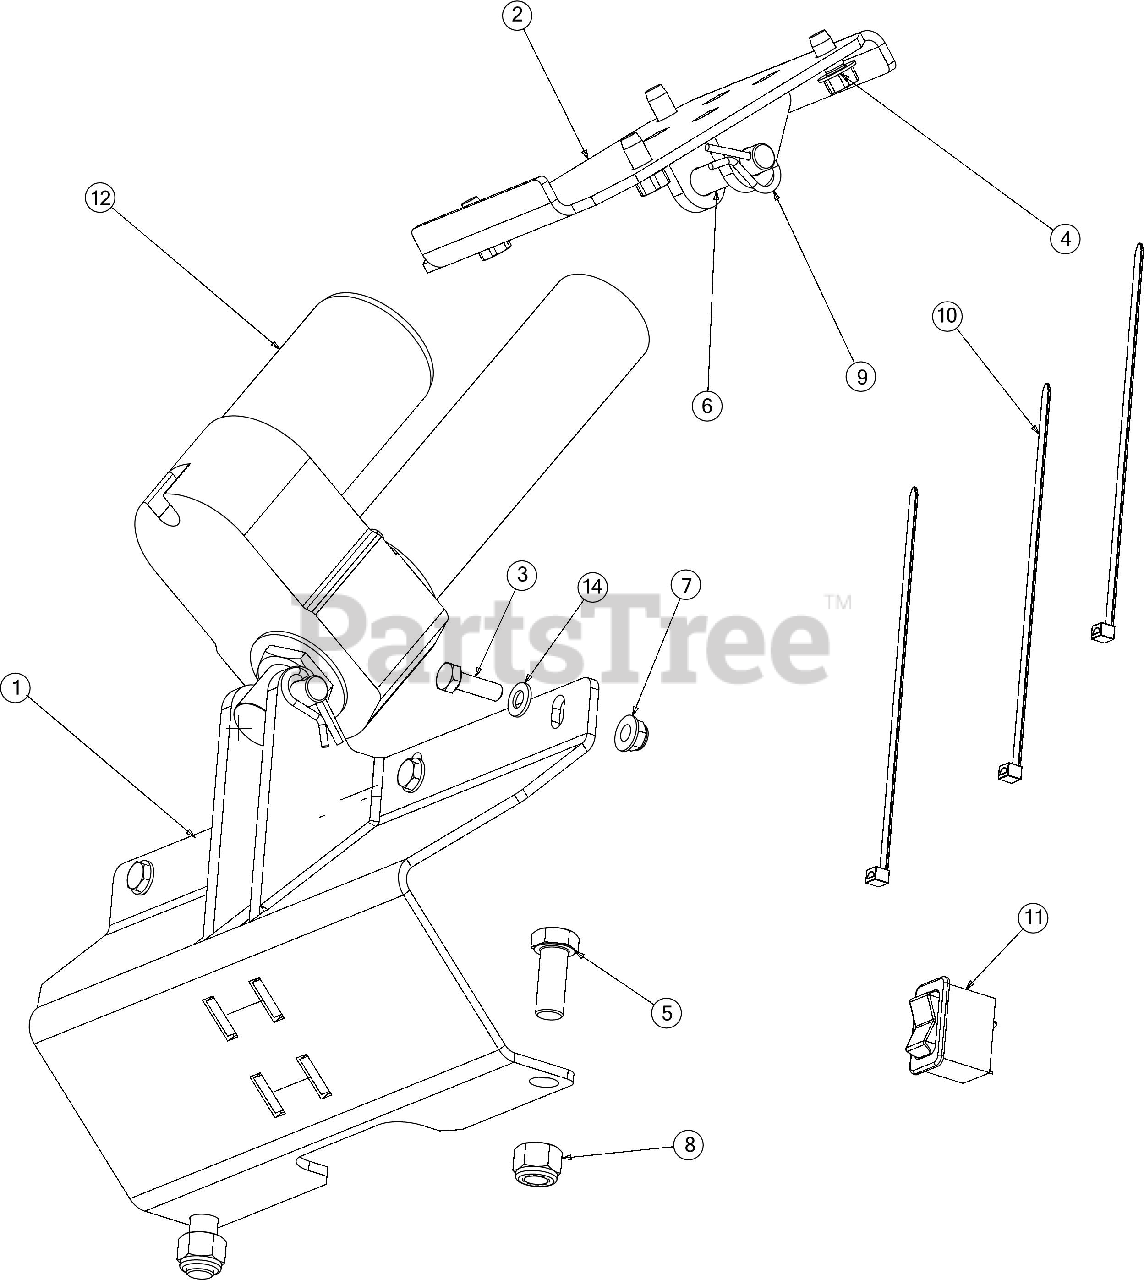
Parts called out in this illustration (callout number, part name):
1	MOUNT PLATE ASSEMBLY
2	BED LIFT PLATE ASSEMBLY
3	SCREW 5/16-18 x 1.0 GR5
4	SCREW 3/8-16 x 3/4
5	SCREW 1/2-13 x 1.25 GR5
6	CLEVIS PIN .50X2.25
7	FLANGE LOCK NUT 5/16-18
8	HEX LOCK NUT NYLON
9	COTTER PIN
10	7" CABLE TIE
11	BED LIFT SWITCH
12	LINEAR ELECTRIC ACTUATOR
14	FLAT WASHER
